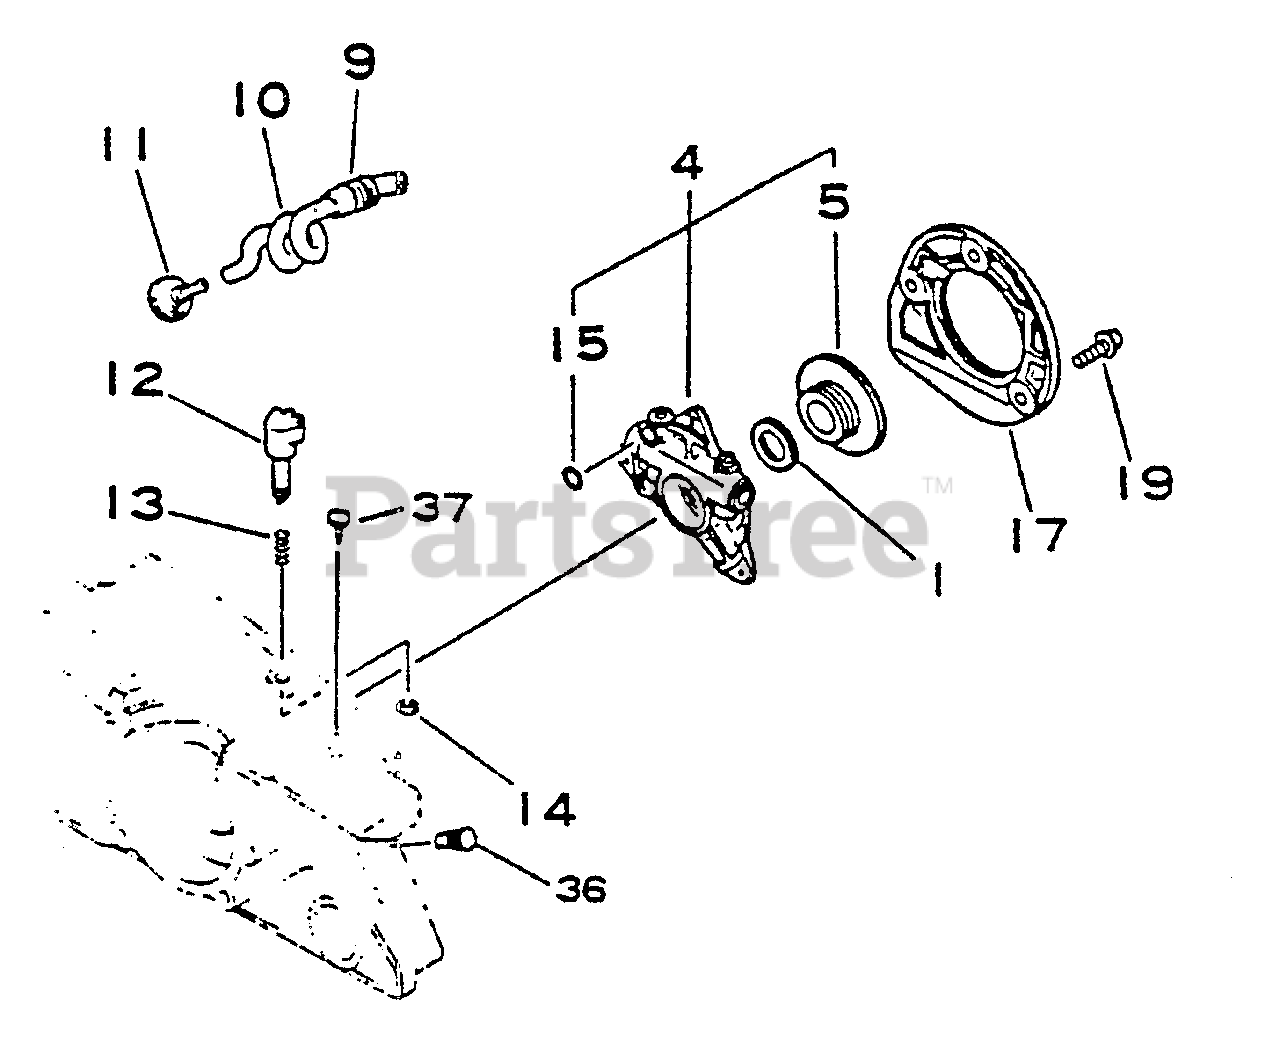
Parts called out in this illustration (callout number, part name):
4	AUTO-OILER ASSY
5	GEAR, WORM
10	PIPE, OIL
11	FILTER, OIL
14	E-RING 3
15	O-RING 3
17	COVER, OIL PUMP - ORANGE
19	SCREW - 4×14
36	PLUG
